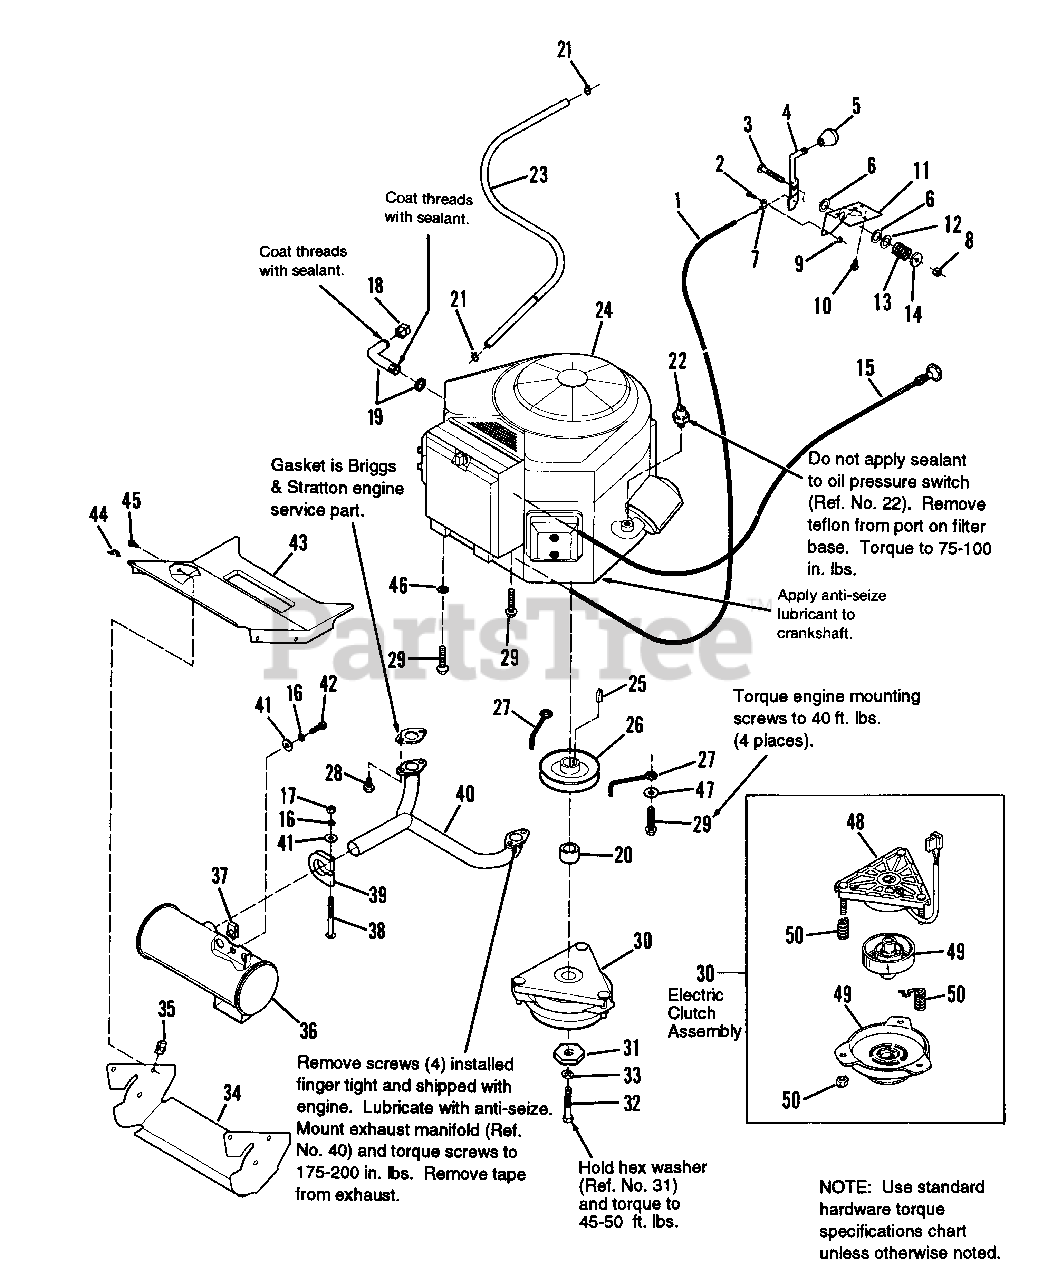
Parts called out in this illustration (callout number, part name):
1	CABLE, Throttle
2	SCREW, Trusshead, 10-32 x 1/2
3	CARRIAGE BOLT, 5/16-18 x 1-3/4
4	HANDLE, Throttle (Incl. Ref. No. 4)
5	KNOB, Throttle
6	WASHER, Nylon
7	CLIP, Bowden Wire
8	NUT, Hex, Lock, Esna Light, 5/16-18
9	NUT ASSY., 10-32
10	SCREW, Plastite, 1/4-20 x 5/8
11	BRACKET, Throttle Mounting
14	WASHER, Plain, 5/16
15	CABLE, Choke Control
16	LOCKWASHER, 5/16
17	NUT, Hex, Full, 5/16-18
21	CLAMP, Hose
22	SWITCH, Oil Pressure
23	HOSE, Fuel, 45.5" Long
24	ENGINE, Briggs & Stratton
25	KEY, Hi-Pro
26	PULLEY ASSY.
28	SCREW, Metric
29	SCREW, Taptite, 3/8-16 x 1-1/2
30	ELECTRIC CLUTCH (Incl. Ref. Nos. 48-50)
32	CAPSCREW, 7/16-20 x 4
33	LOCKWASHER, 7/16
34	DUCT, Lower Muffler
35	NUT, Pal, 1/4-20
36	MUFFLER ASSY.
37	NUT, Pal, 5/16-18
38	CARRIAGE BOLT, 5/16-18 x 2-3/4
39	CLAMP, Mumer
40	MANIFOLD, Exhaust
41	WASHER, Plain, 11/32
42	CAPSCREW, Hex Hd., 5/16-18 x 1
43	DUCT, Upper Muffler
44	CLIP
45	SCREW, Flange Whiz, 1/4-20 x 5/8
46	LOCKWASHER, External Tooth
47	WASHER, Plain, 13/32
48	FIELD ASSY., Clutch
49	ROTOR ASSY./ARMATURE KIT
50	SPRING & NUT KIT
